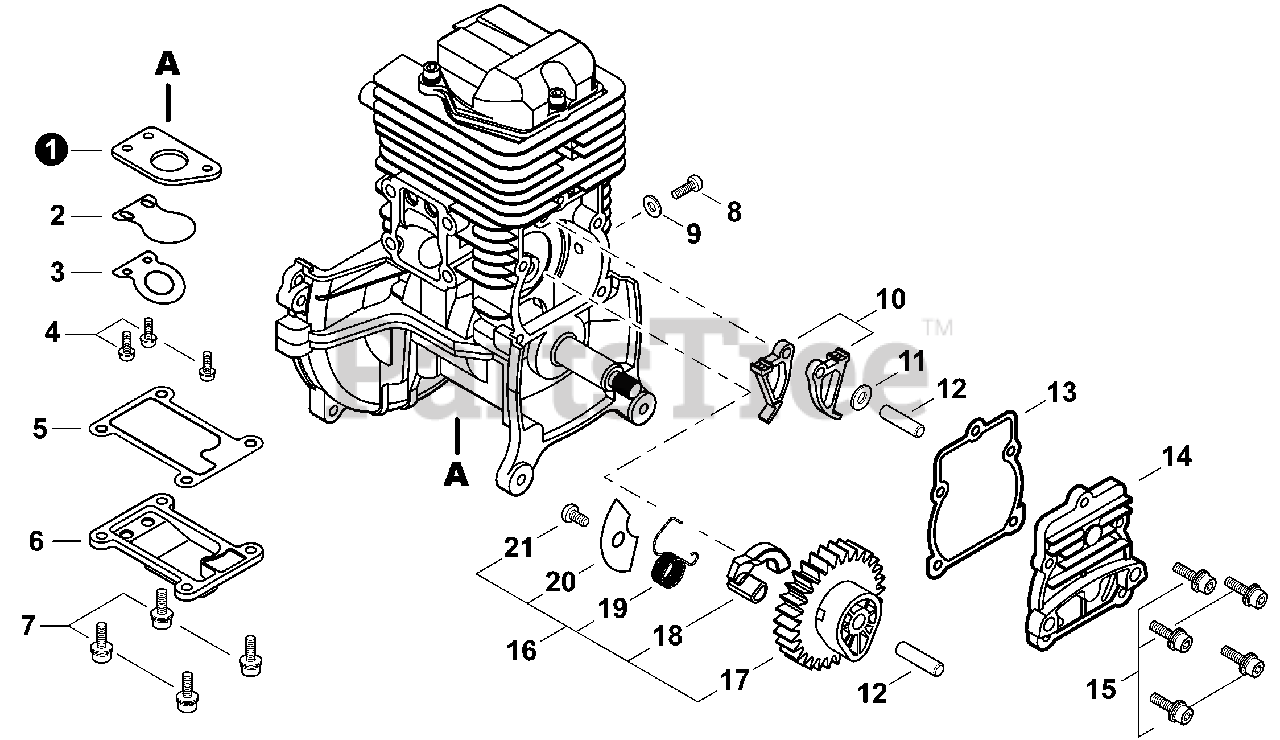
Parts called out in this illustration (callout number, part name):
1	PLATE, REED BACKING
2	VALVE, REED
3	STOP, REED VALVE
4	SCREW M3x10
5	GASKET, REED VALVE
6	COVER, REED VALVE
7	BOLT M4x12
8	SCREW M5
9	WASHER ?10x?5.5x2
10	FOLLOWER, CAM
11	WASHER 5 MM
12	PIN, LOCATING ?5x29.8 MM
13	GASKET, CAM GEAR
14	COVER, CAM GEAR
15	BOLT M4x14
16	CAM GEAR ASSY
17	GEAR, CAM
19	SPRING, COIL
20	PLATE, COVER
21	SCREW, TAPPING 4x6
